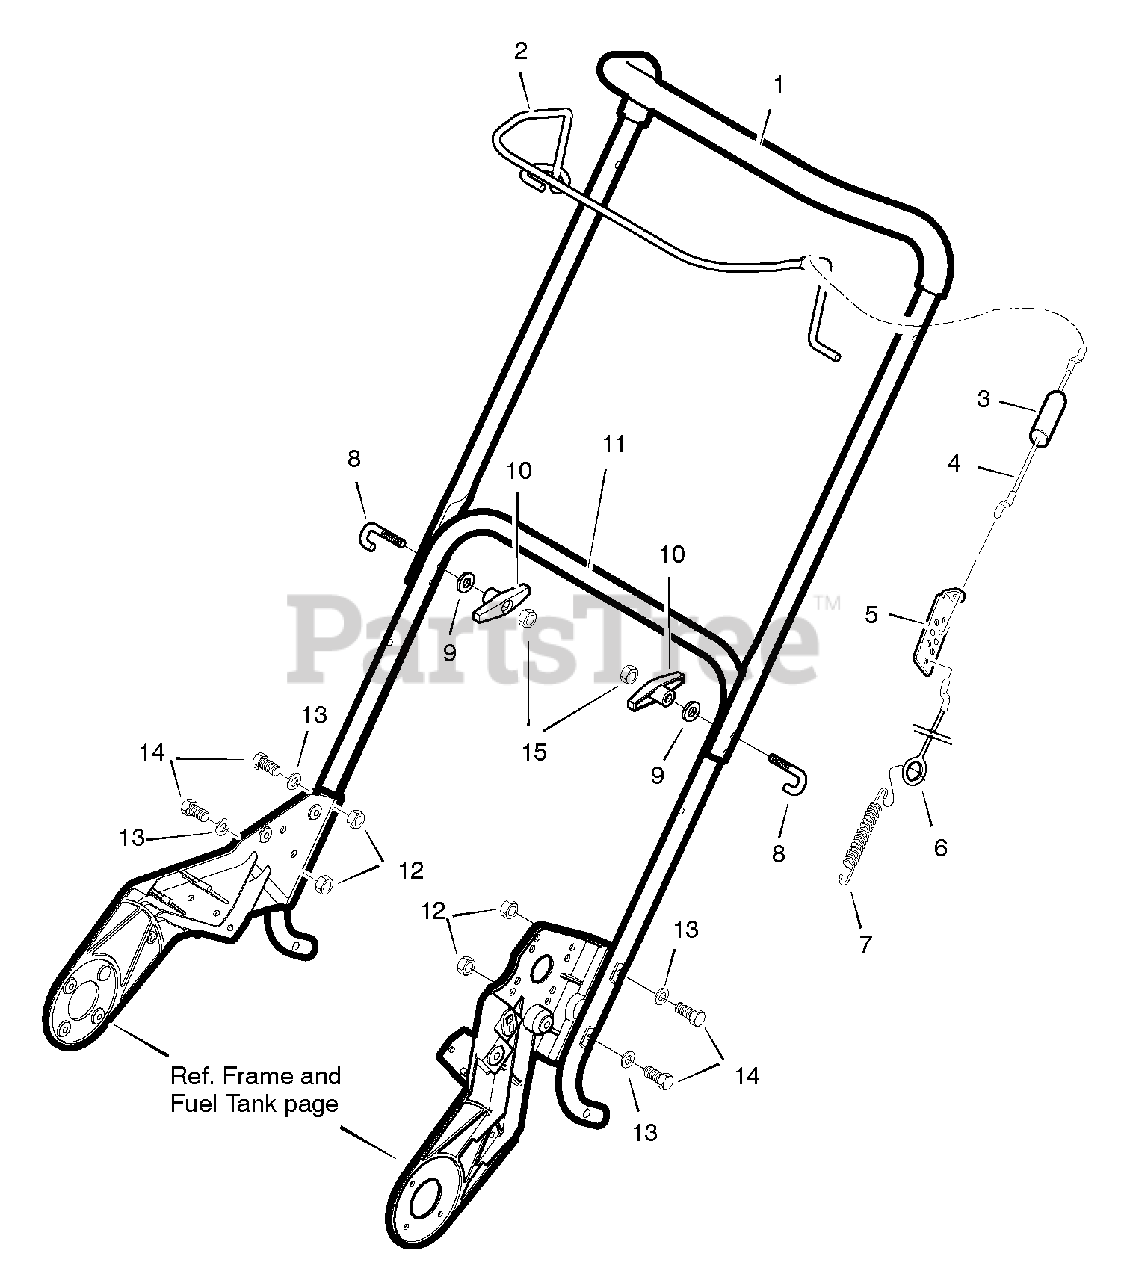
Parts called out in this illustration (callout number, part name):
1	Handle & Grip Assembly
2	Control, Bail
3	Boot, Clutch Spring
4	Cable, Upper Control
5	Bracket, Control Adjust
6	Cable, Lower Control
10	Knob, Wing
11	Handle, Lower
13	Washer
14	Screw, 1/4-20 x1.25
15	Nut, 5/16-18
